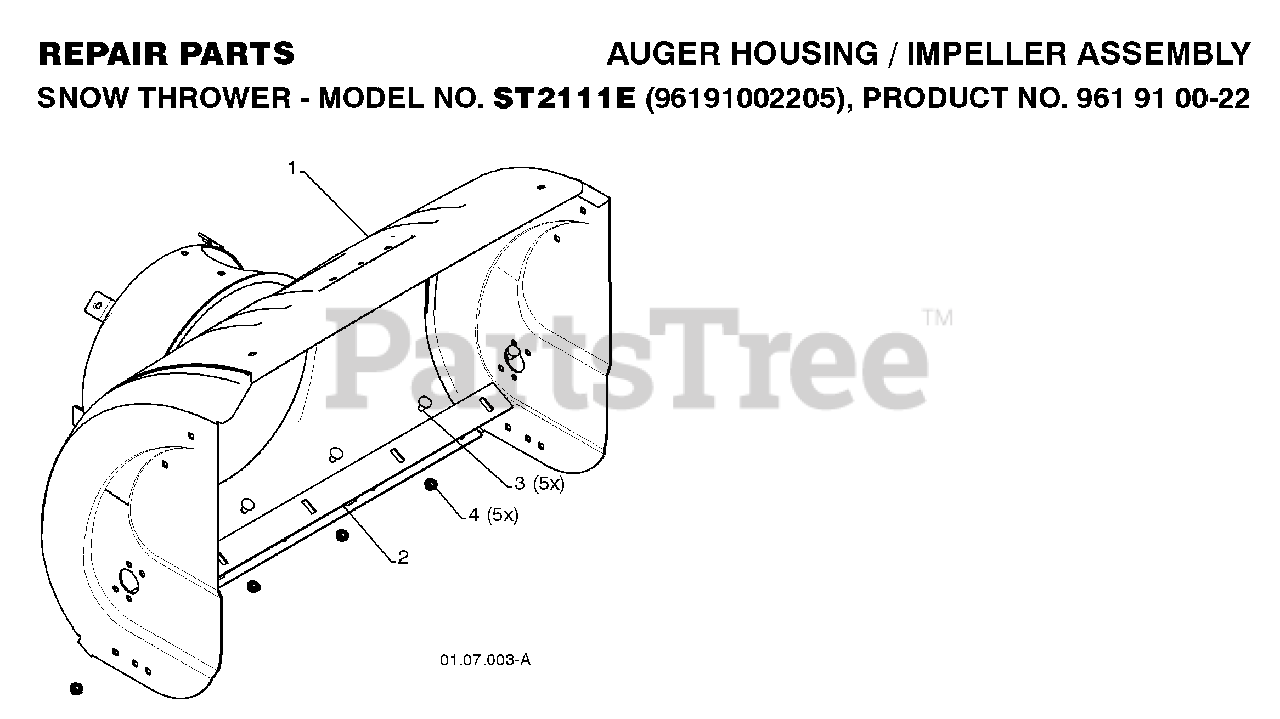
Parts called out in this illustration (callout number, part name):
2	BAR, SCRAPER
3	BOLT
4	NUT.FLANGE.5/16
